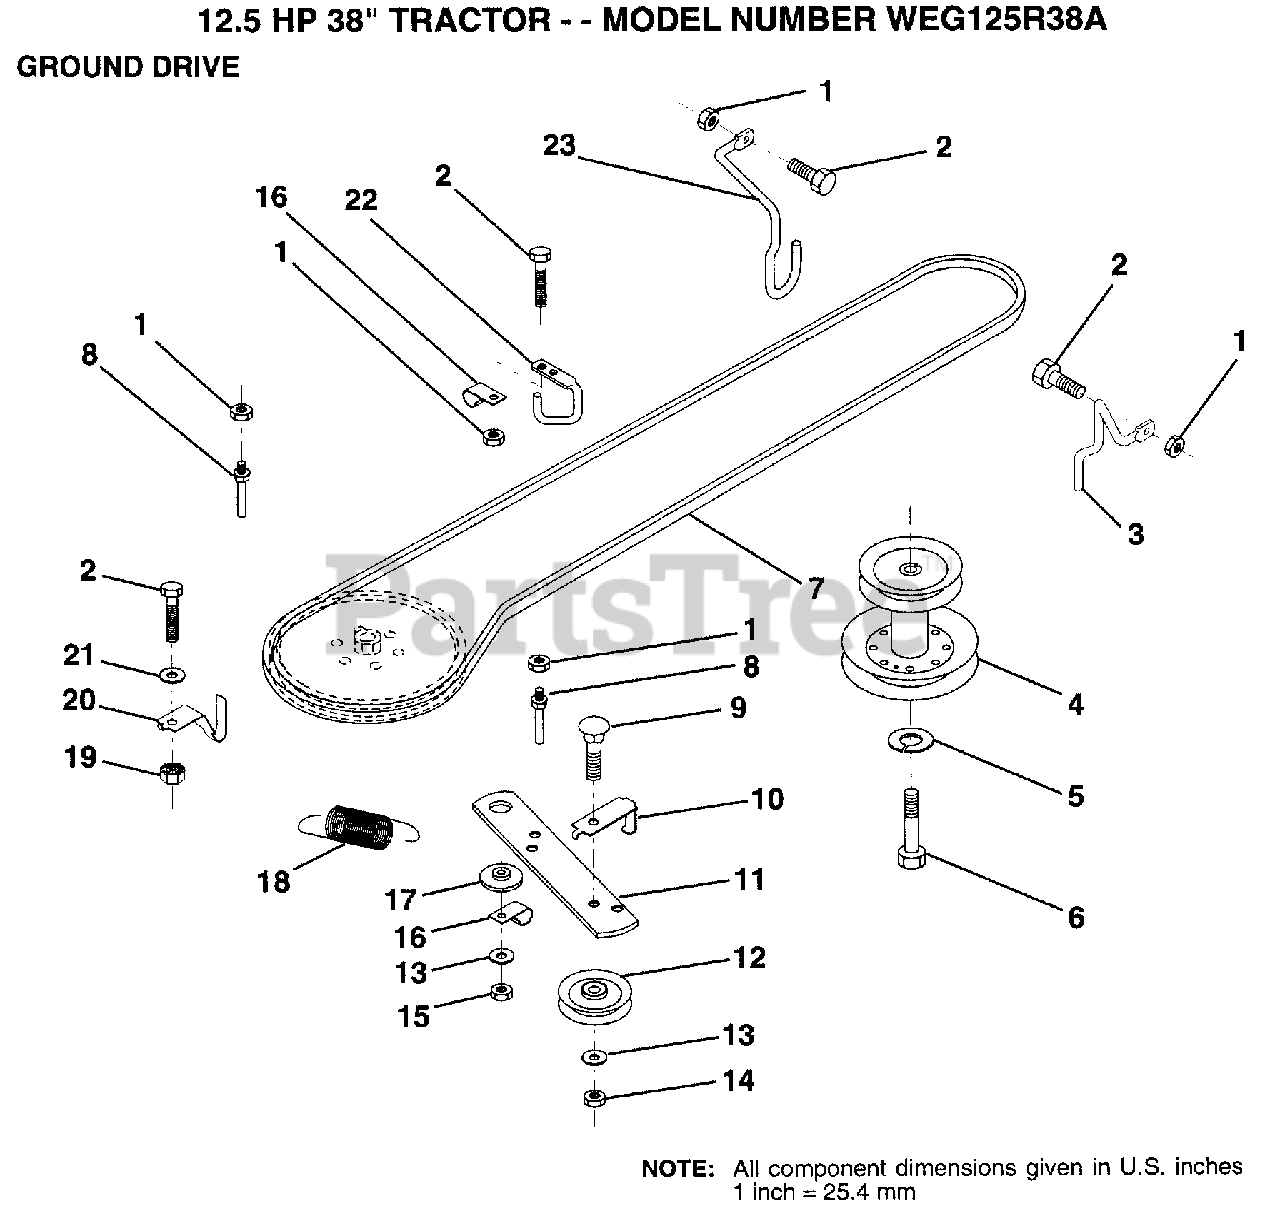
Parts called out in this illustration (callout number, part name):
1	NUT
2	BOLT
3	KEEPER.BELT.FRT.
4	PULLEY.ENGINE.LR
5	LOCKWASHER
6	HEX BOLT
7	BELT
8	"KEEPER,DRIVE BELT"
9	BOLT
10	"KEEP,IDLER DR BEL"
11	ARM IDLER CLUT GD
12	PULLEY.IDLER.FLAT
13	WASHER
14	LOCKNUT
15	NUT
16	CLIP INSULATOR
17	SPACER RETAINER
20	KEEPER.BELT.T/A
22	"KEEPER,FRA DR BEL"
23	KEEPER.BELT.FRT.L
